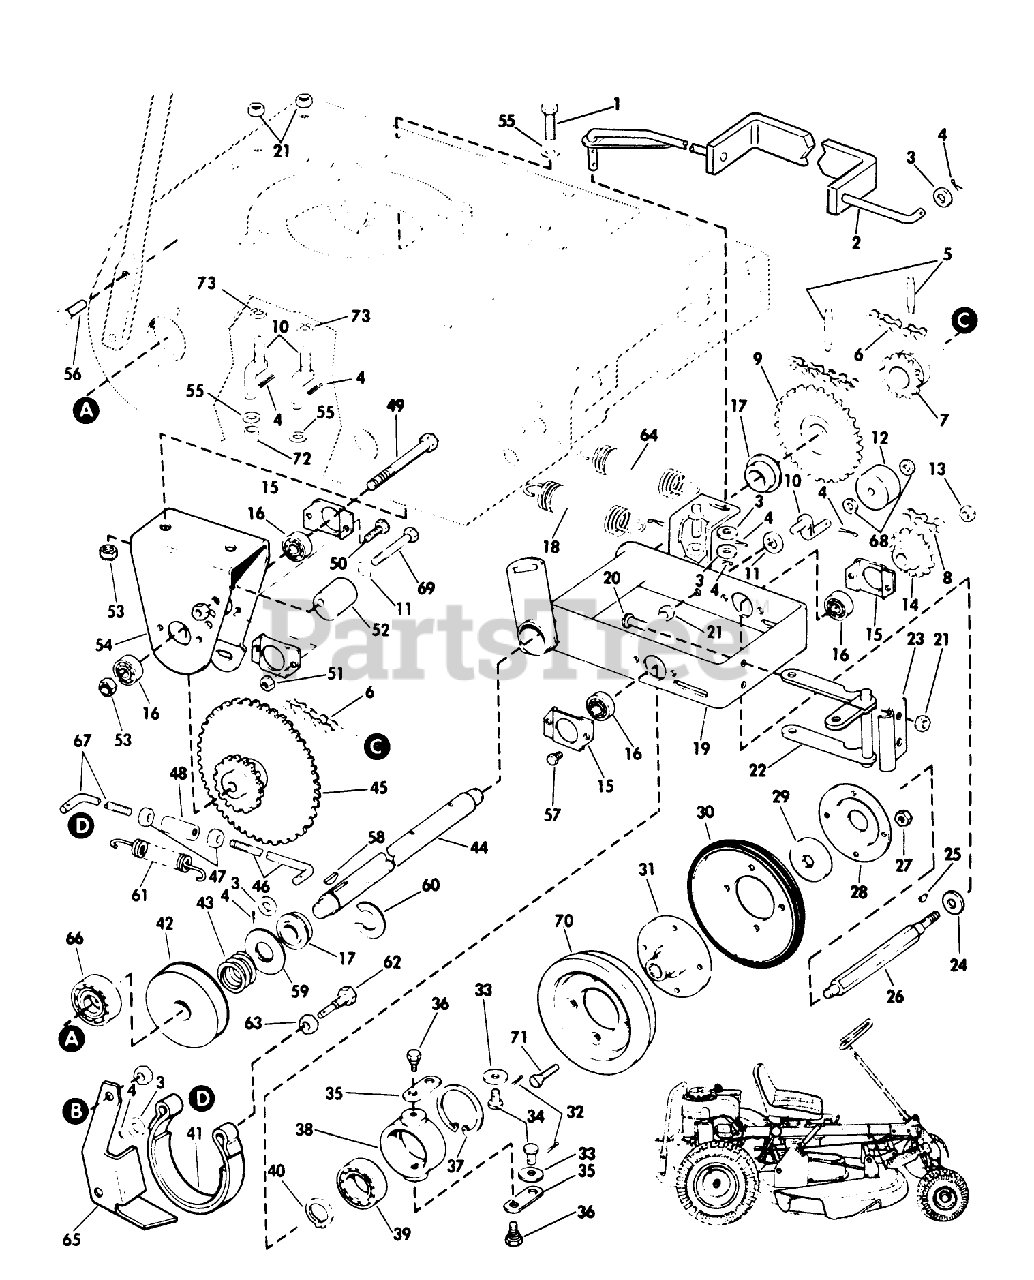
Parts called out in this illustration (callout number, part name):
13	LOCKNUT
47	STOP NUT
53	LOCKNUT
